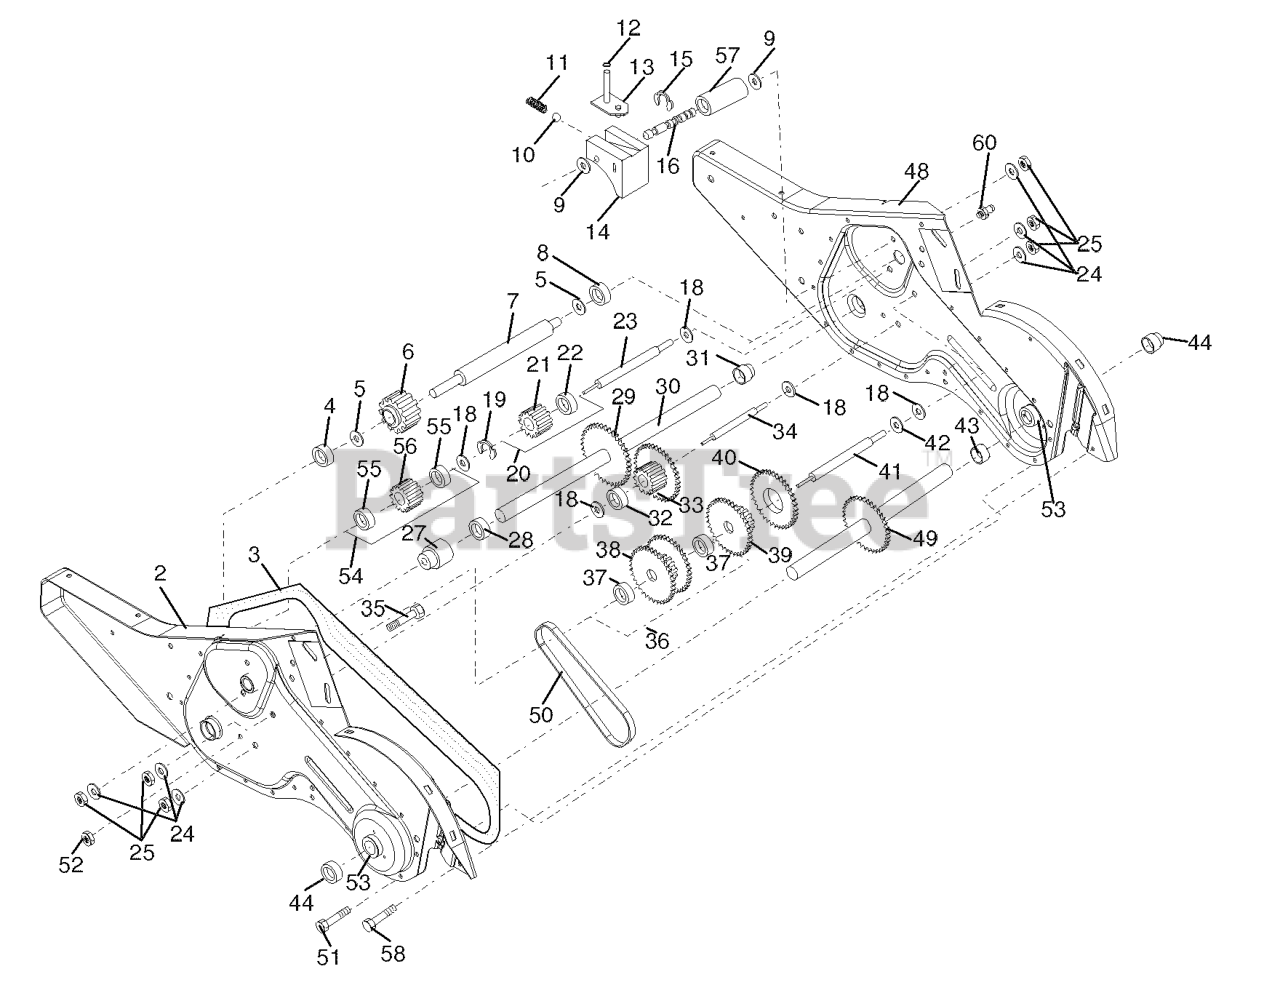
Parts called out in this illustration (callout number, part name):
1	TRANSMISSION.ASM.17
2	GEARCASE.ASM.DRT.LH.
3	GASKET
4	NEEDLE BRNG LT
5	THRUST WASHER
6	GEAR.PINION.INPUT.DRT
7	SHAFT.INPUT.D.9TEETH
9	WASHER, SEAL (2 2)
10	BALL, STEEL
11	SPRING-SHIFT CRT
13	BRACKET ASM.SHIFT.CRT
14	SHIFT FORK TI
16	SHAFT.SHIFT.DRT
20	GEAR ASSY CRT
21	GEAR-REV IDLR CRT
22	NEEDLE BEARING TI
23	SHAFT.IDLER.REVERSE.CRT
24	LOCKWASHER
25	NUT.ASF.HEX.7/16
27	BEARING, SHAFT, GROUNDDRIVE LH
30	GROUND SHAFT ASS'Y
31	BEARING, SHAFT RH CRT
33	SPRCKT 8 GEAR CRT
34	SHAFT.SECONDARY.REDUCTION.CRT
35	SCRW WHIZ LOK CRT
36	GEAR & SPROCKET.ASM.WBEARIN
37	BEARING.NEEDLE.CRT
38	ASM.GEAR & SPROCKET
39	GEAR.CLUSTER.DRT.TILLER
41	SHAFT.REDUCTION.FIRST.DRT
42	BRNG RACE T
44	SEAL ASM, OIL
48	GEARCASE.ASM.DRT.RH.
49	TINE SHAFT
50	CHAIN.TILLER
51	SCREW
52	NUT
53	KIT.BEARING.TILLER.
54	GEAR.ASM.DRT.TILLER
55	BEARING.NEEDLE
56	GEAR.DRT.IDLER
57	SPACER.SPLIT
58	BOLT SHOULDER 1/4-20 UNC X.875
60	FITTING.GREASE.TAPERED
60	GREASE CARTRIDGE
